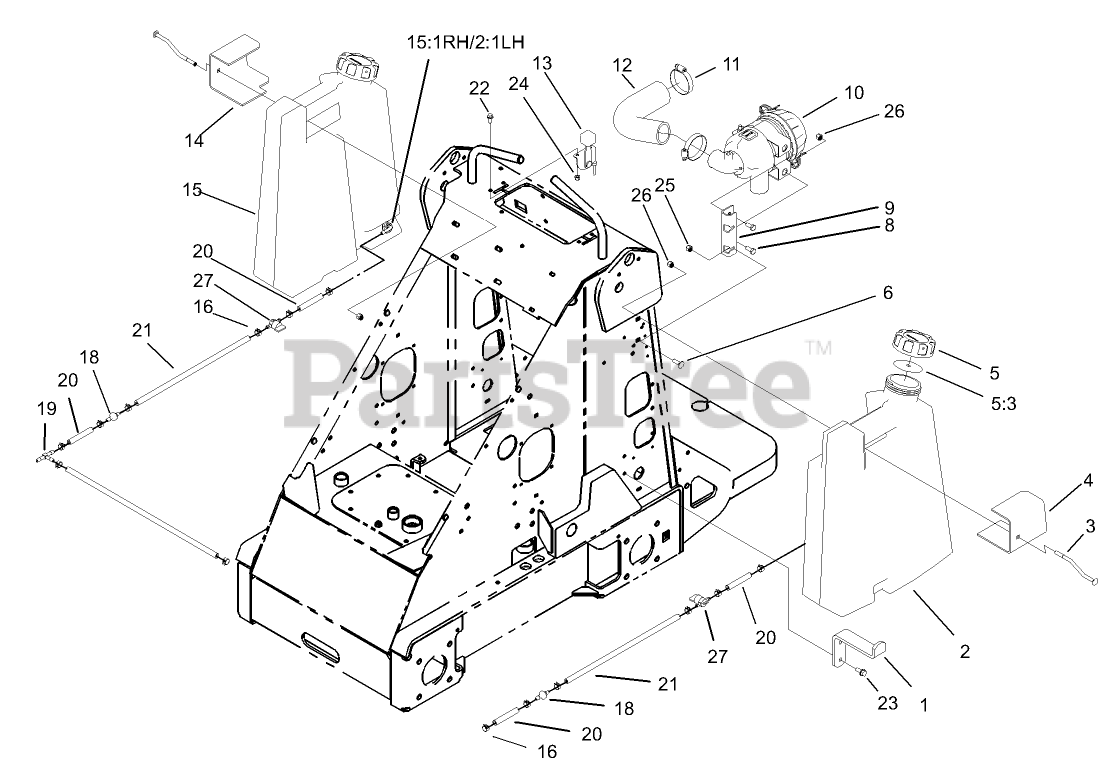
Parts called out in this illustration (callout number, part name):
1	MOUNT-BOTTOM, TANK
2	LH Fuel Tank ASM
2:1	FITTING-FUEL, BULKHEAD
3	BOLT-MOUNT
4	PLATE-MOUNT, LEFT
5	CAP-FUEL, GAS
5:3	GASKET-VENTED
6	BOLT-CARR
8	SCREW-HH
9	MOUNT-CLEANER, AIR
10	AIR CLEANER ASM
11	CLAMP-HOSE
12	HOSE-AIR
13	CONTROL-CHOKE / THROTTLE
14	PLATE-MOUNT
15	RH Fuel Tank ASM
15:1	FITTING-FUEL, BULKHEAD
16	CLAMP-HOSE
17	HOSE-FUEL
18	VALVE-CHECK, FUEL
19	FITTING-TEE, BARBED
20	HOSE-FUEL
21	HOSE-FUEL
22	SCREW-HHF
23	SCREW-HWHTF
24	NUT-LOCK, NI
25	NUT-HF
26	NUT-LOCK, NI
27	VALVE-FUEL
